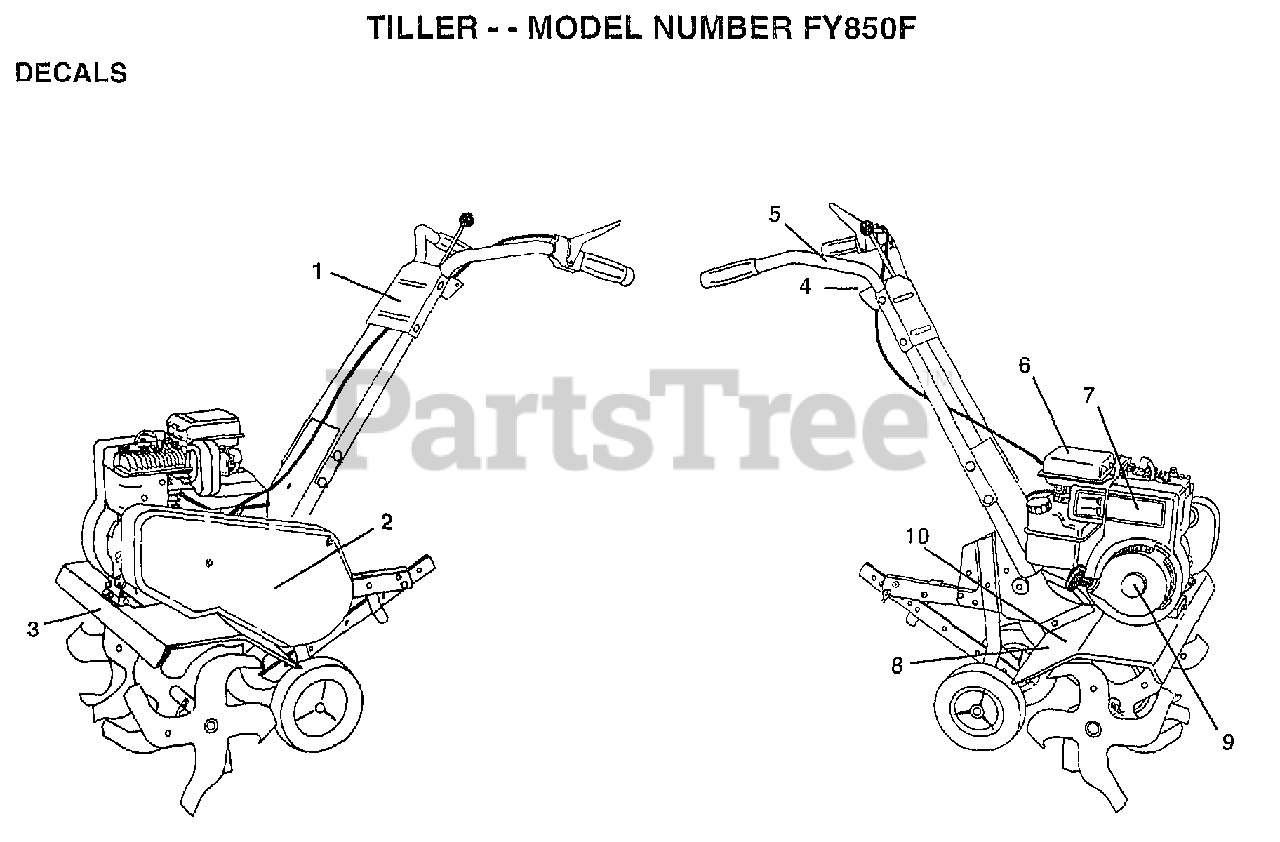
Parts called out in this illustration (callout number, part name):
1	DECAL HANDLE BRKT
2	DECAL.BELT.GUAR
3	DECAL TINE SHIELD
4	DECAL REVERSE
5	DECAL TI
6	DECAL TI
7	DECAL, BRIGGS & STRATTON
10	DECAL.CAUTION
